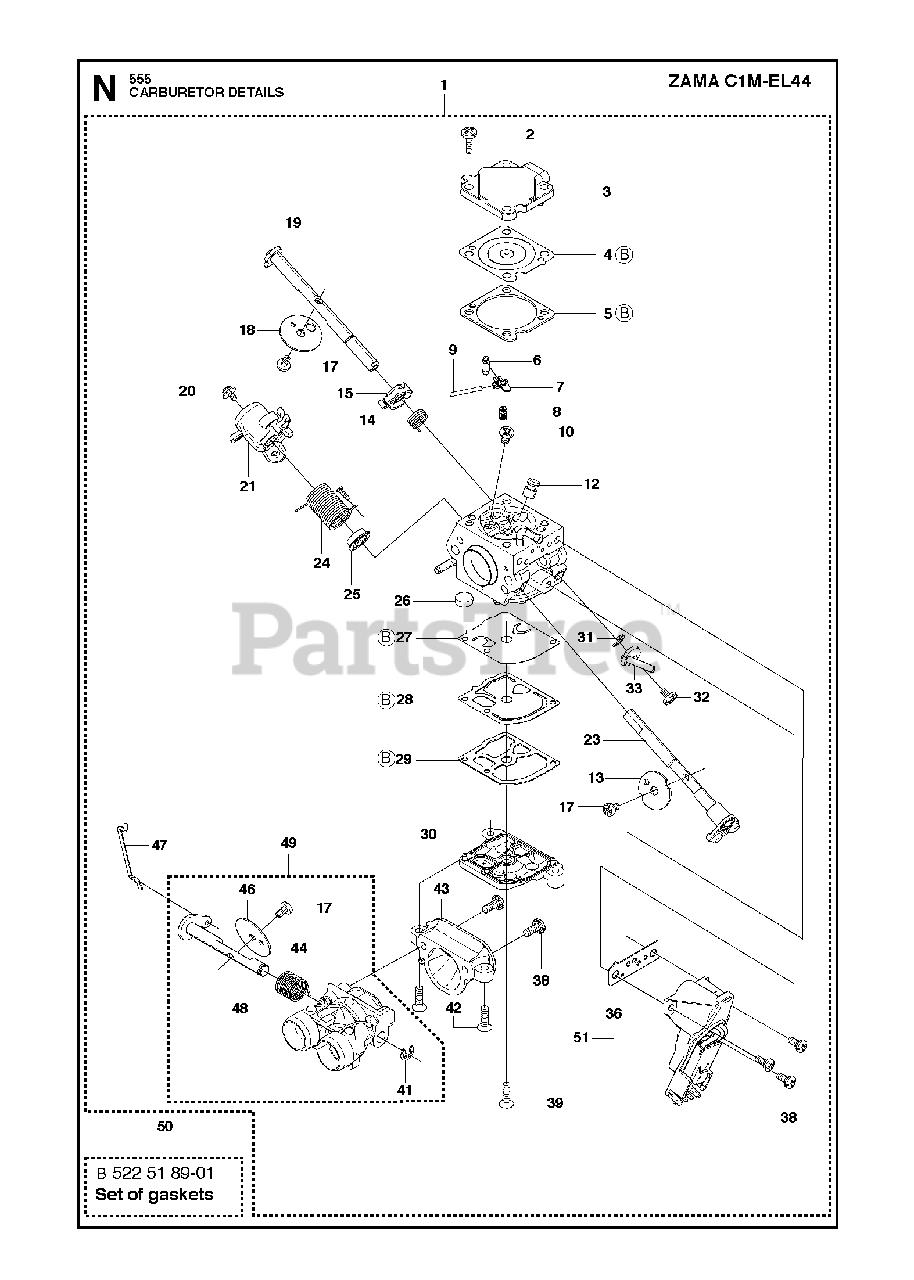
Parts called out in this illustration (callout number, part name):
1	CARBURETTOR
2	SCREW
3	COVER
4	DIAPHRAGM
5	GASKET
6	INLET NEEDLE
7	LEVER
8	SPRING
9	PIN FULCRUM
10	SCREW
12	MAIN NOZZLE
13	VALVE
14	SPRING
15	LEVER
17	SCREW
18	CHOKE VALVE
19	SHAFT ASSY
20	SCREW
21	THROTTLE LEVER
23	THROTTLE SHAFT
24	SPRING
25	COLLAR
26	STRAINER
27	PUMP DIAPHRAGM
28	DIAPHRAGM
29	GASKET
30	COVER
31	CIRCLIP
32	SCREW
33	CHOKE LEVER
36	GASKET CARBURETTOR
38	Screw
39	SCREW
41	CLIP
42	SCREW
43	INLET
44	SPRING
46	THROTTLE FLAP
47	ROD
48	SHAFT ASSY
49	THROTTLE VALVE ASSY
50	KIT GASKET AND DIAPHRAM
51	SPARE PARTS KIT
